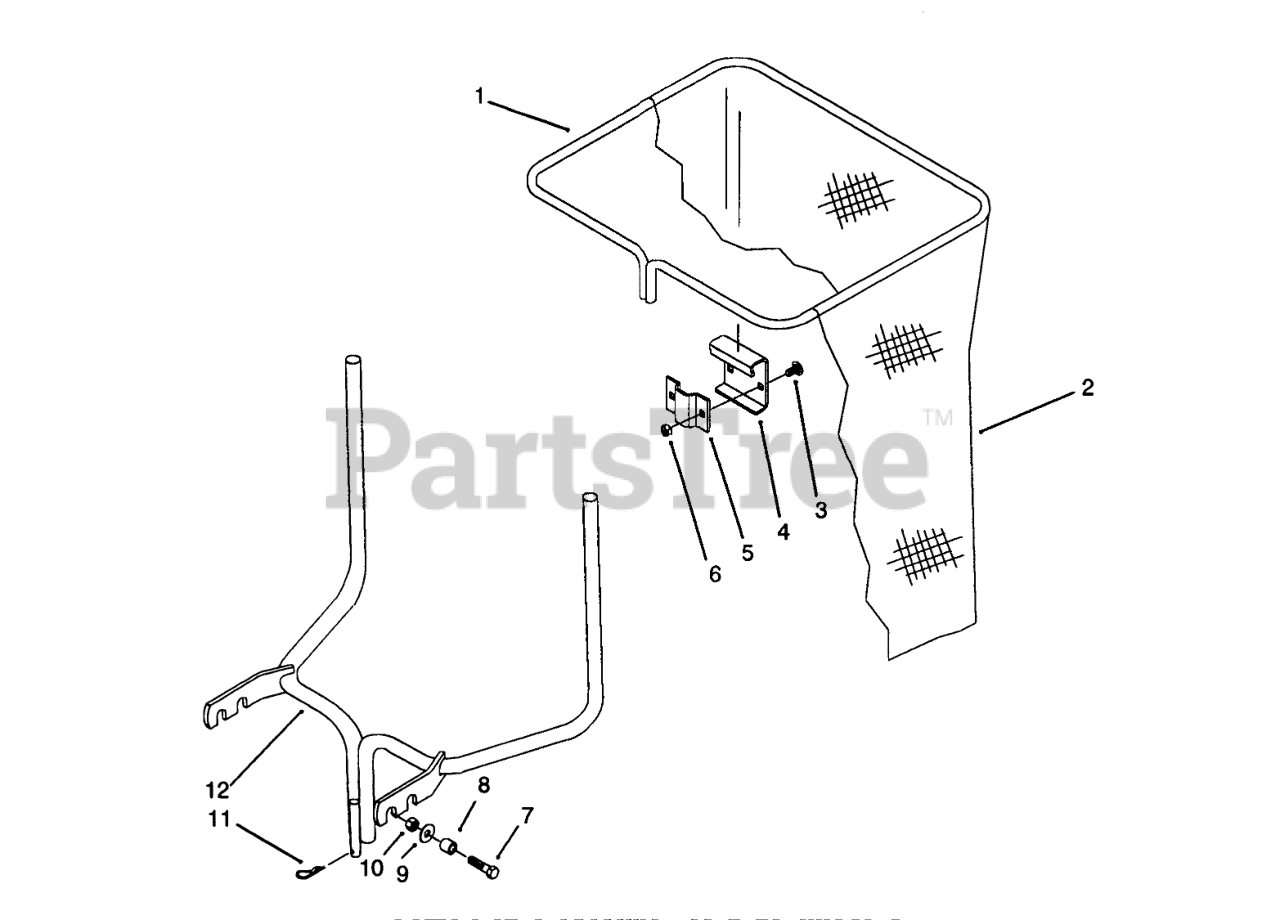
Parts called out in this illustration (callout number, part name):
1	Bag Frame
2	Bag
3	BOLT-CARR
4	Bag Hanger
5	Clamp
6	NUT-LOCK, NI
7	SCREW-HH
8	SPACER
9	WASHER
10	NUT-LOCK, NI
11	Hairpin
12	Bracket-Quick Attach
